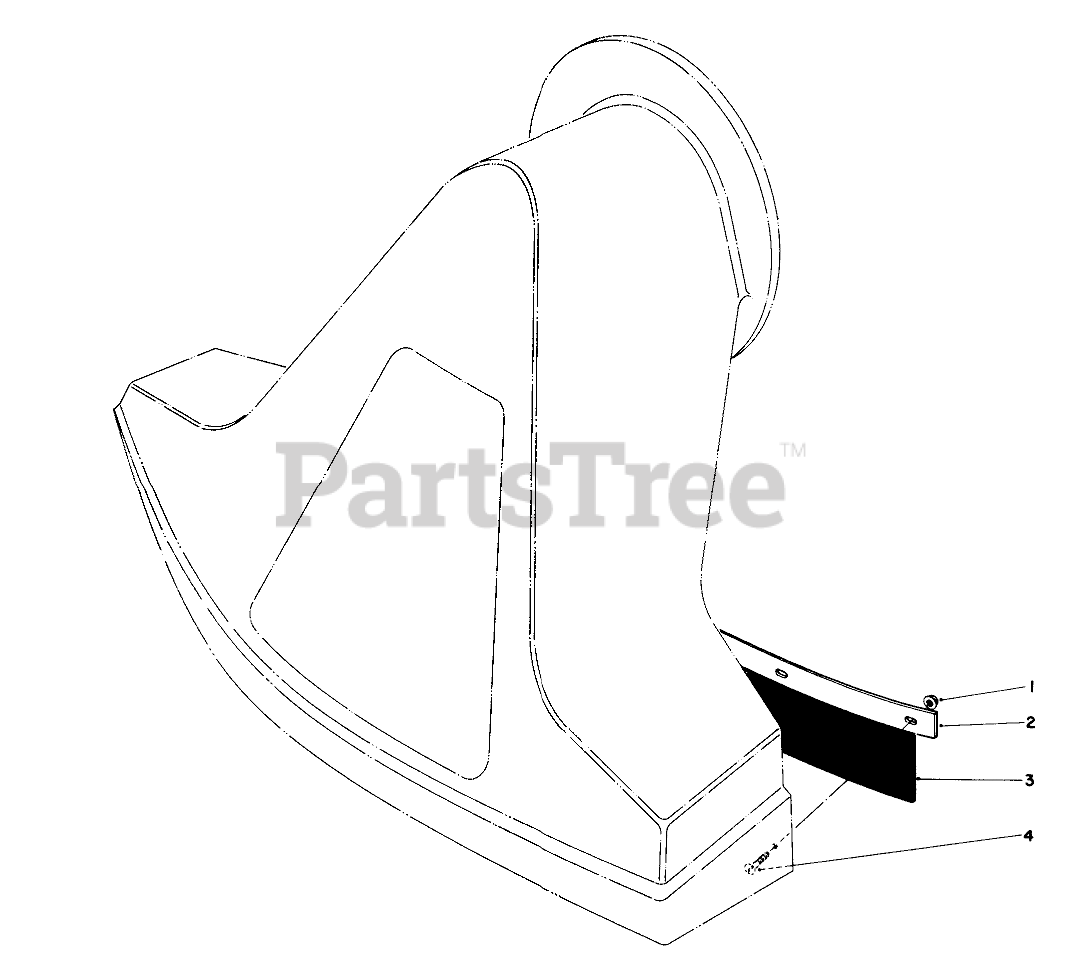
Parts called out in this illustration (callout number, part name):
1	NUT-LOCK, FLANGE
2	Clamp-Flap
3	FLAP-RUBBER
4	10-24 X 5/8 PAN HD MS
